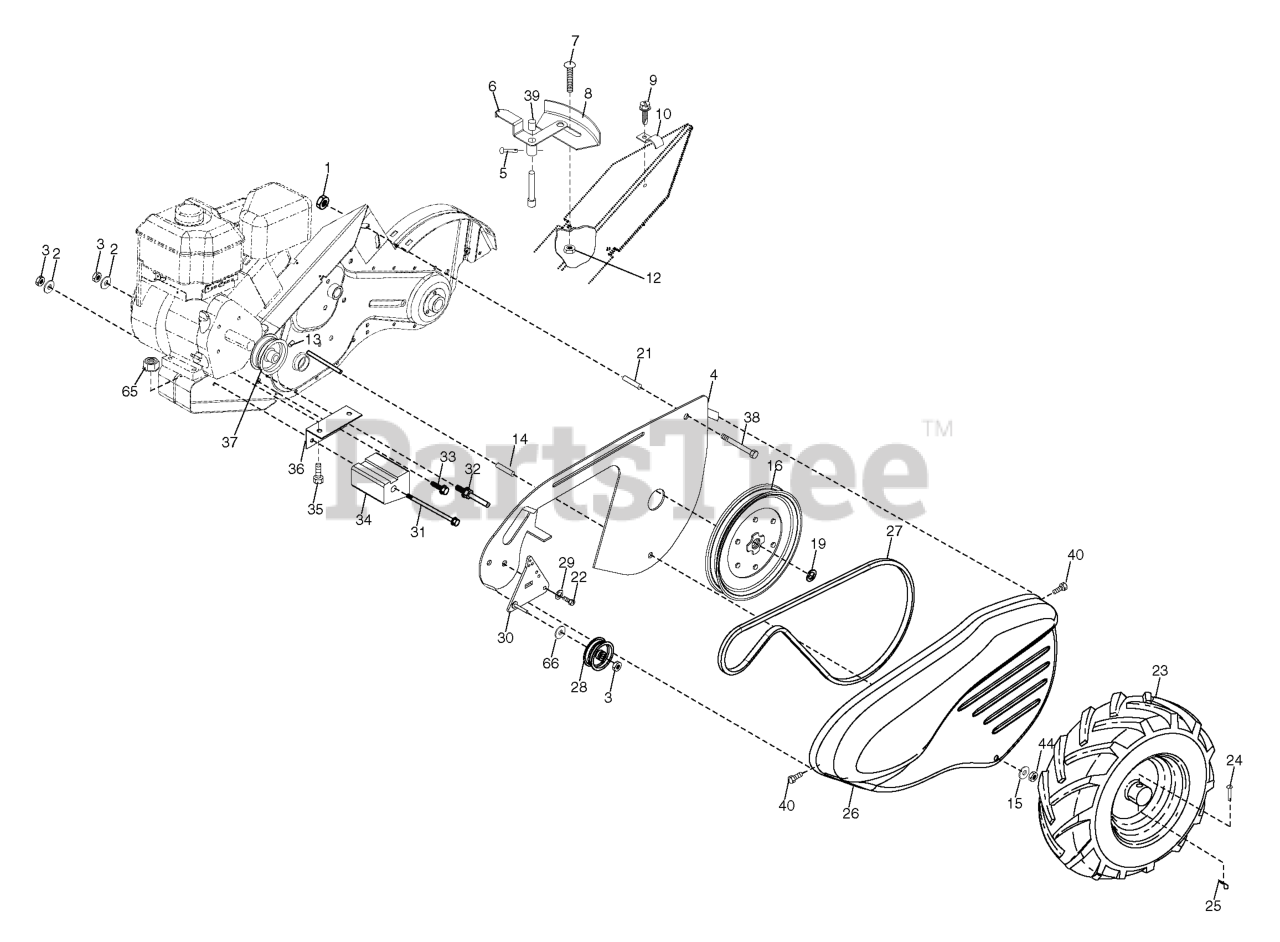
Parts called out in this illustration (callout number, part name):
1	NUT
2	WASHER, LOCK 3/8
3	NUT.HEX.3/8-16UNC
4	SHIELD
5	PIN.SPIROL.FLARED
6	LEVER ASM CRT
8	PANEL.INDICATOR.SHIFT.BLACK
9	TAPPING SCREW
10	CONDUIT.CLIP.PLATED
12	NUT
14	SPACER-SPLIT.327 X .42
15	WASHER
16	SHEAVE, TRANSMISSION
19	RETAINING RING LT
21	SPACER CRT
23	TIRE.13X5-6.CHEVRON.TILLER
23	RIM.ASM.6".SILVER
23	VALVE STEM LT
24	RIVET,DRILLED
25	RETAINER M
26	RP BELT GUARD
27	V-BELT
28	PULLEY-IDLER TI
30	BRACKET.ASM.IDLER.BLACK
31	BOLT.FIN.HEX.3/8-16UNC
32	SHIFT ARM CRT
33	BOLT
34	COUNTERWEIGHT.LH.CRT
35	BOLT
36	BRACKET LH CRT
37	RP.ENGINE PULLEY
38	BOLT
39	CAP.PLUNGER.BLACK
40	SCREW.HEX.WSH.SLT.#10-24X.50
44	NUT.71038.31-18.HEX.NYLOCK
65	LOCKNUT-FLANGE 5/16-18
66	WASHER
